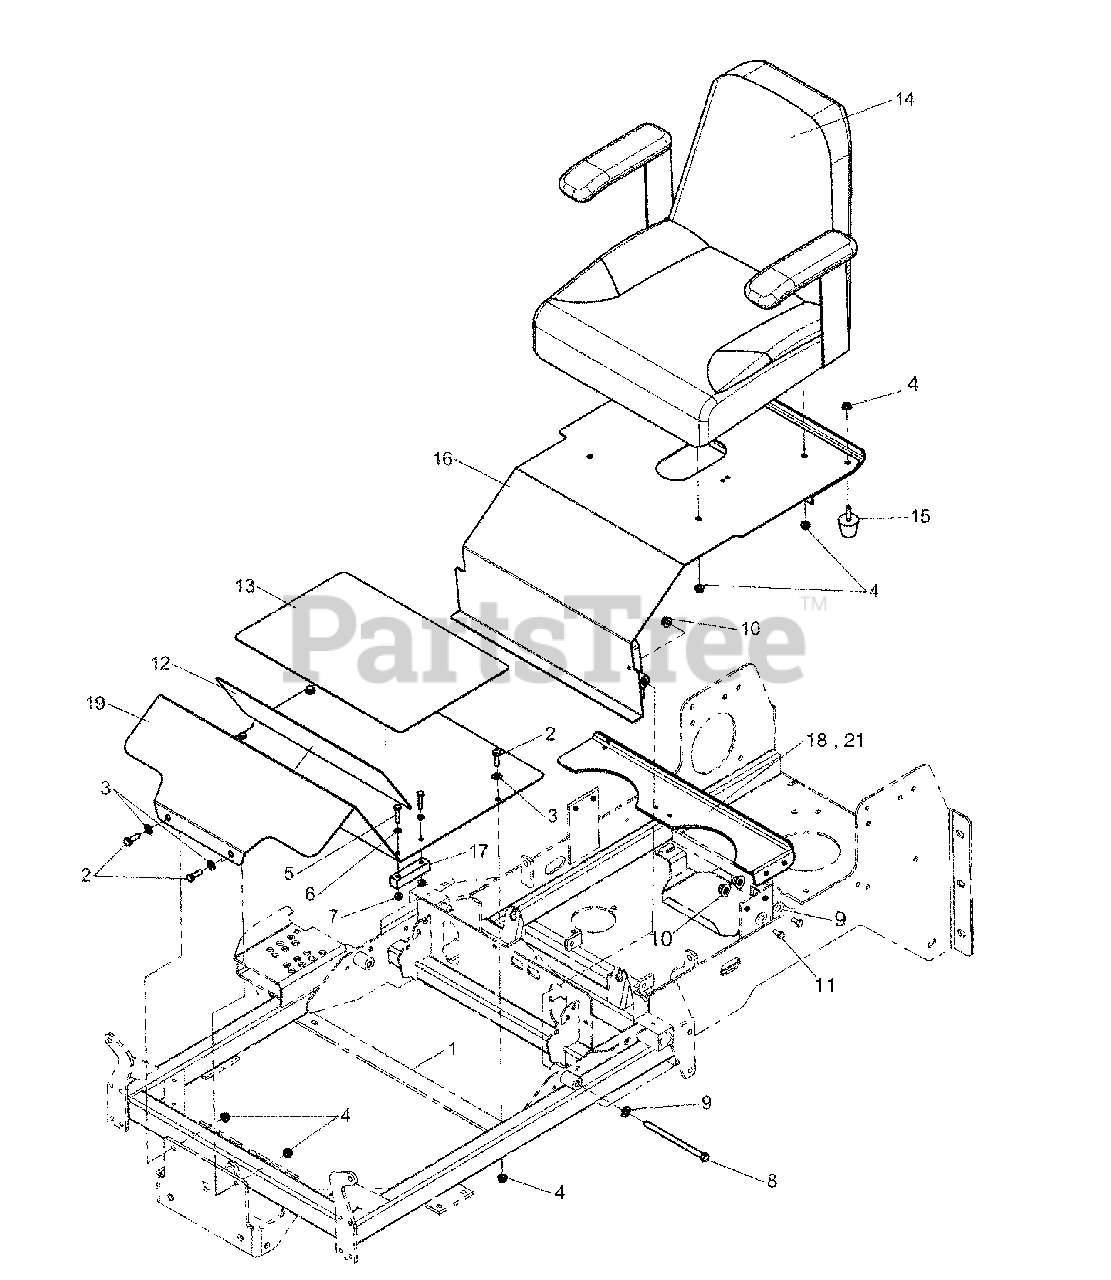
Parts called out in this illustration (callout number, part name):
1	MAIN FRAME
2	BOLT, 5/16-18 X 1
3	WASHER 5/16" Gr. 9 Flat
4	NUT, 5/16-18 Hex Nylock Flange
5	BOLT, 1/4-20 X 1-1/4
6	WASHER, 1/4 SAE (5025154)
7	NUT, 1/4-20 HEX NYLOCK FLANGE (5025391)
8	BOLT, 3/8-16 X 6
9	WASHER, 3/8 SAE
10	NUT, 3/8-16 Hex Nylock Flange
11	BOLT, 3/8-16 X 1" GD5 YZ
12	SAFETY WALK, FLOOR REST
13	SAFETY WALK, FLOOR PLATE
14	SEAT, BLACK
15	RUBBER BUMPER
16	SEAT PLATE
17	BLOCK, DECK LIFT SUPPORT
18	SUPPORT, SEAT PLATE
19	PLATE, FLOOR
20	ARM REST (SET OF 2)
21	PLATE, SEAT SUPPORT - ORG
